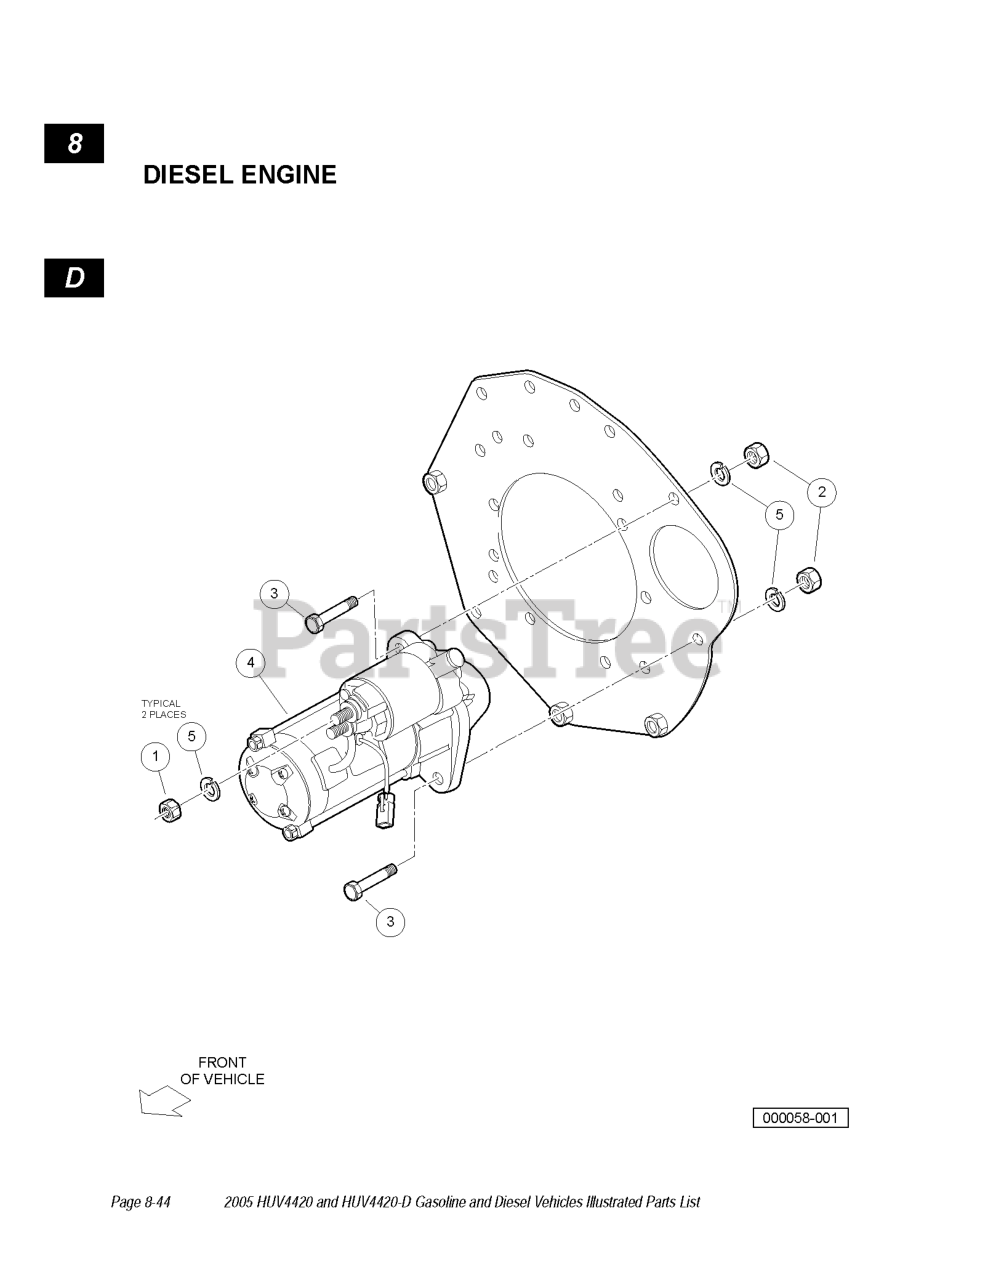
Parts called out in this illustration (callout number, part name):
1	2UT, D722 STARTER
2	NUT-ALT-LOWER
3	BOLT, M8 X 1.25 X 28
4	ASSY, STARTER WAS 102648501
5	WASHER-ALT-LOCK
